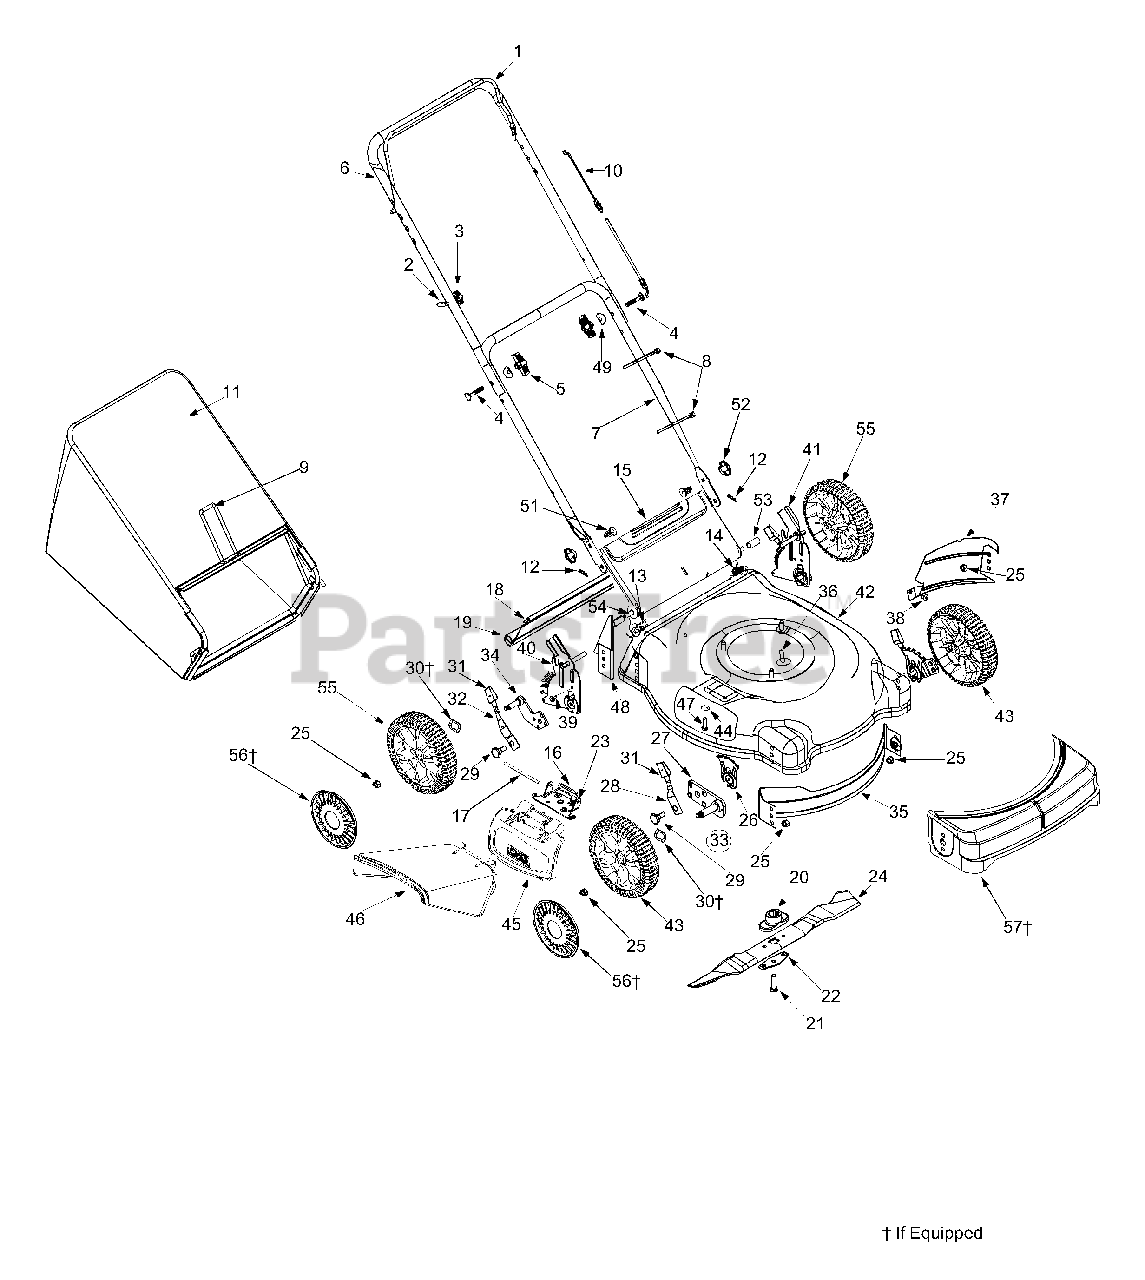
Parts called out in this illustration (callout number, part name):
2	Rope Guide
3	Handle Knob 1/4-20 Thd.
4	Curved Hd. Bolt 5/16-18 x 2"
5	Hand Knob
8	Cable Tie
10	Control Cable - 40"
11	Grass Bag
12	Int. Cotter Pin 5/16" Dia.
13	Door Spring - R.H.
14	Door Spring - L.H.
15	Rear Discharge Door
16	Torsion Spring
17	Hinge Pin
18	Wire Rod
19	Rear Flap
20	Blade Adapter w/Star
21	Hex Bolt 3/8-24 x 1.5" Lg.
22	Blade Bell Support
23	Deflector Chute Adapter
24	21" Mulching Blade w/Star
25	Flange Nut 3/8-16 Thd.
26	Height Adj. Plate
27	Pivot Arm Assembly - RH (8" Wheels)
28	Front Spring Lever
29	Shld. Bolt.5" Dia. x.357"
30	Wave Washer
31	Spring Lever Knob
32	Rear Spring Lever
33	Height Adj. Assy. Comp. - RH (8" Whl)
34	Pivot Arm R.H.
38	Torx Mach AB-Tap Scr. 1/4 x.62"
39	Hex Ind Wash. Scr. 1/4-20:.625
40	Handle Bracket - RH
41	Handle Bracket - LH
44	Bell Washer 1/4" I.D.
45	Hinged Mulching Plug
46	Side Chute Deflector
47	Hex Hd Self-Tp Scr. 1/4-20 x.5"
49	Shoulder Washer
51	Hex Carriage Screw 1/4-20
52	Wing Nut
53	Spacer,.375OD x.50ID
54	Rear Door Pivot Rod
55	Rear Wheel 8" x 1.8"
56	Hub Cap - Radial Spoke Yellow
57	Front Cover
